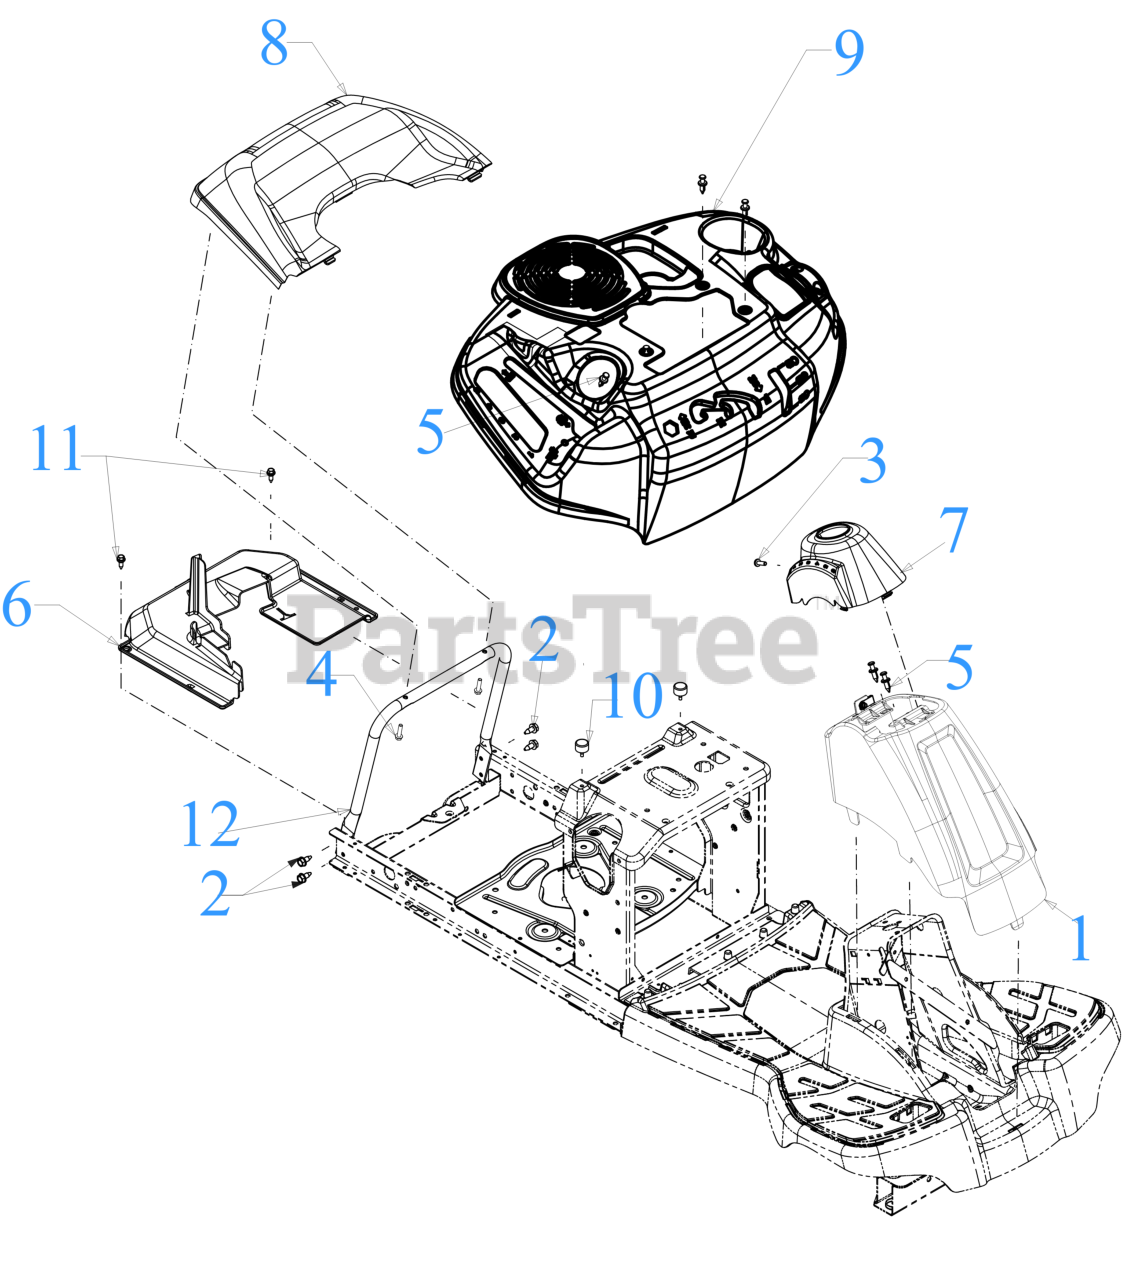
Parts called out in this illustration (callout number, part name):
1	COLUMN COVER (LIBERTY RED)
2	SCREW 5/16-18 x .750
3	SCREW 1/4-20X.75
4	SCREW 1/4-15 x 1.00
5	PLASTIC RIVET
6	DRIVE OVER REAR
7	STEERING COLUMN CAP (LIBERTY RED)
8	REAR COVER (LIBERTY RED)
9	FENDER (B&S W/RMC) (LIBERTY RED)
10	BUMPER .62 DIA x .50
11	SHOULDER SCREW
